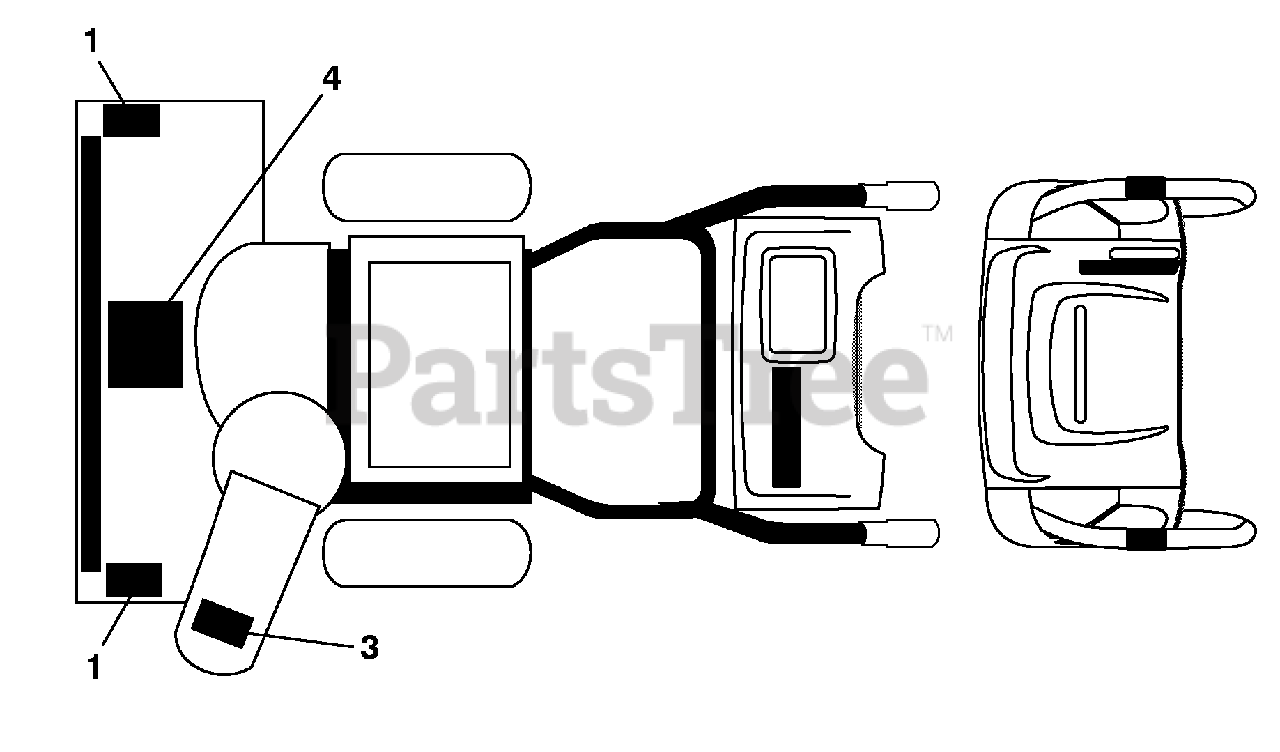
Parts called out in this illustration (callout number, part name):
1	DECAL, DANGER
3	DECAL, DANGER, DEFLECTOR
4	DECAL, DANGER
4	OWNER'S MANUAL, ENGLISH / SPANISH
